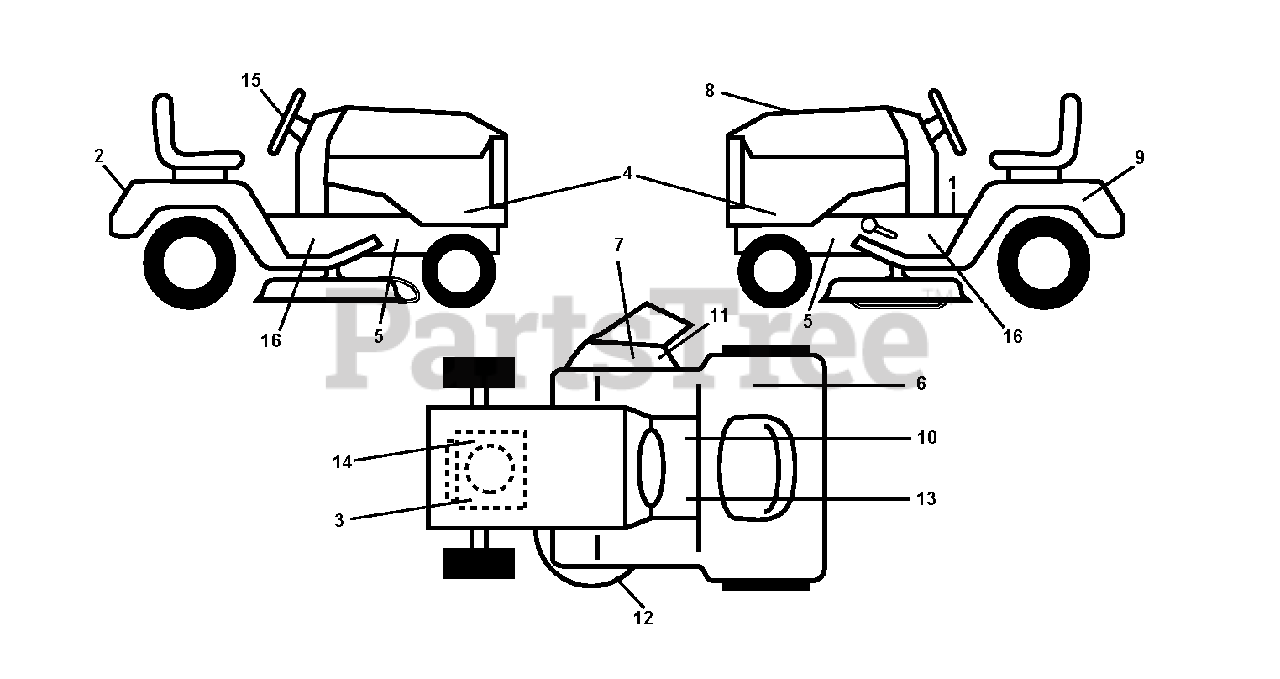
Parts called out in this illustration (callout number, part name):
7	DECAL.INTERNATIONL.CUTFINGER
9	DECAL BTRY SYMBOLS
10	DECAL PARK BRAKE
11	DECAL, DEFLECT WARNING
12	DECAL.V-BELT.SCHEMATIC.36/38/9
